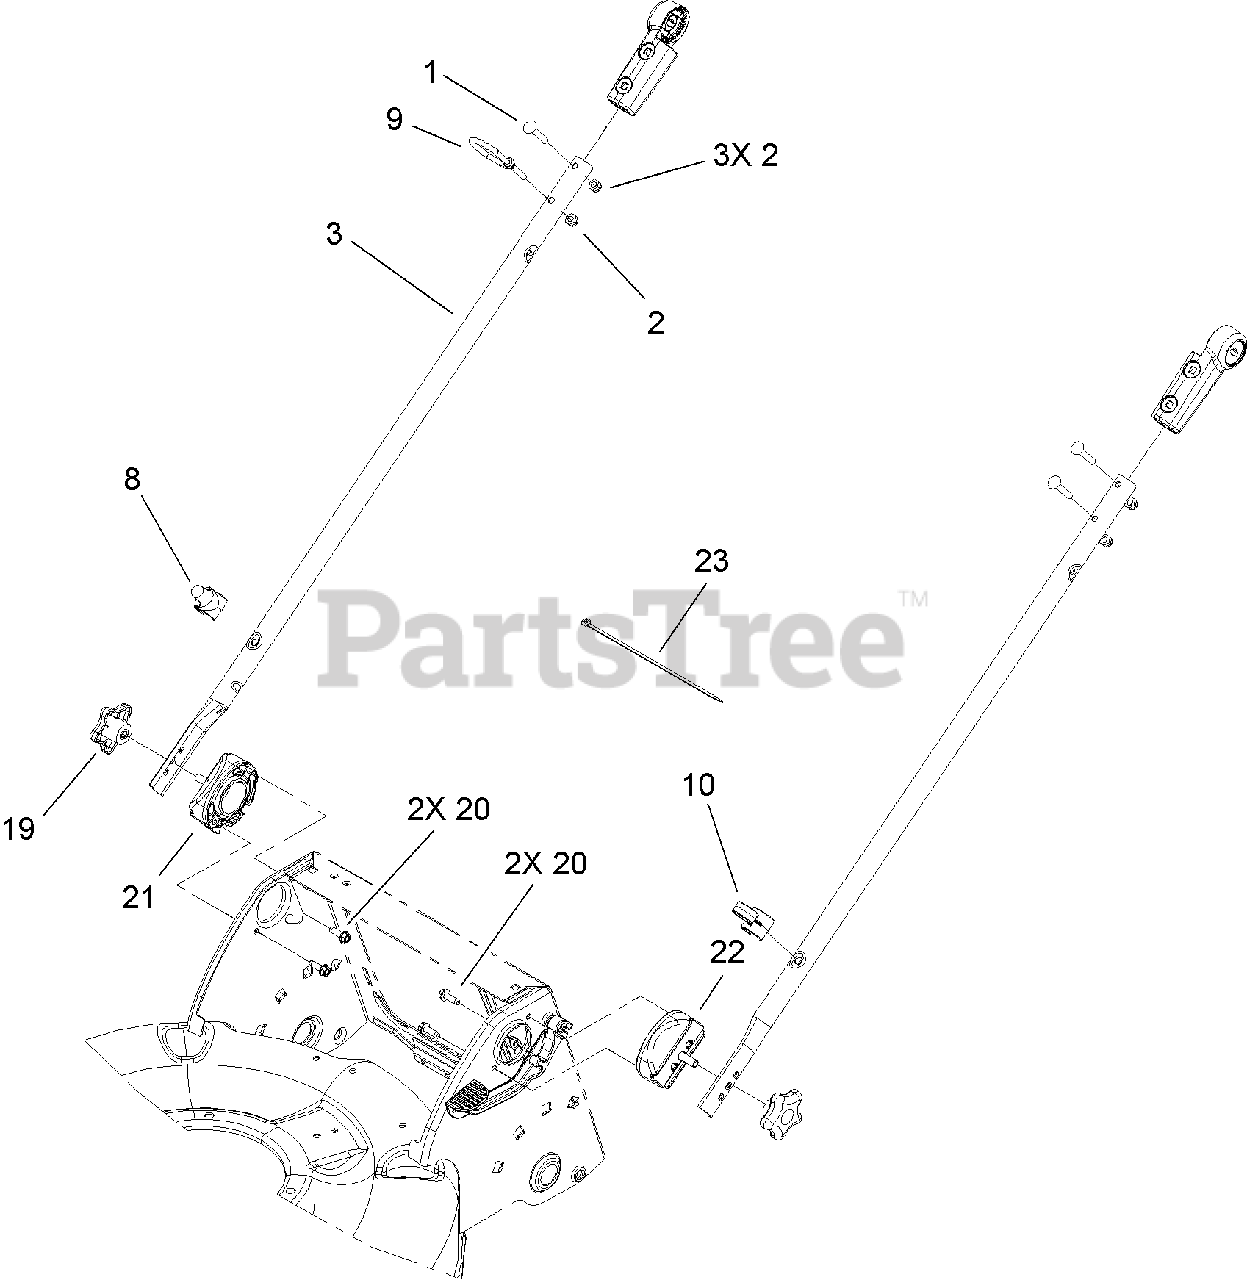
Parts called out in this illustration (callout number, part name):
1	SCREW-CARR
2	NUT-LOCK, NI
8	GUIDE-ROPE, LOWER
9	GUIDE-ROPE, UPPER
10	Guide-Cable
19	KNOB-HANDLE
20	SCREW-HWHTF
21	RH HANDLE MOUNT ASM
22	LH HANDLE MOUNT ASM
23	STRAP-TIE
